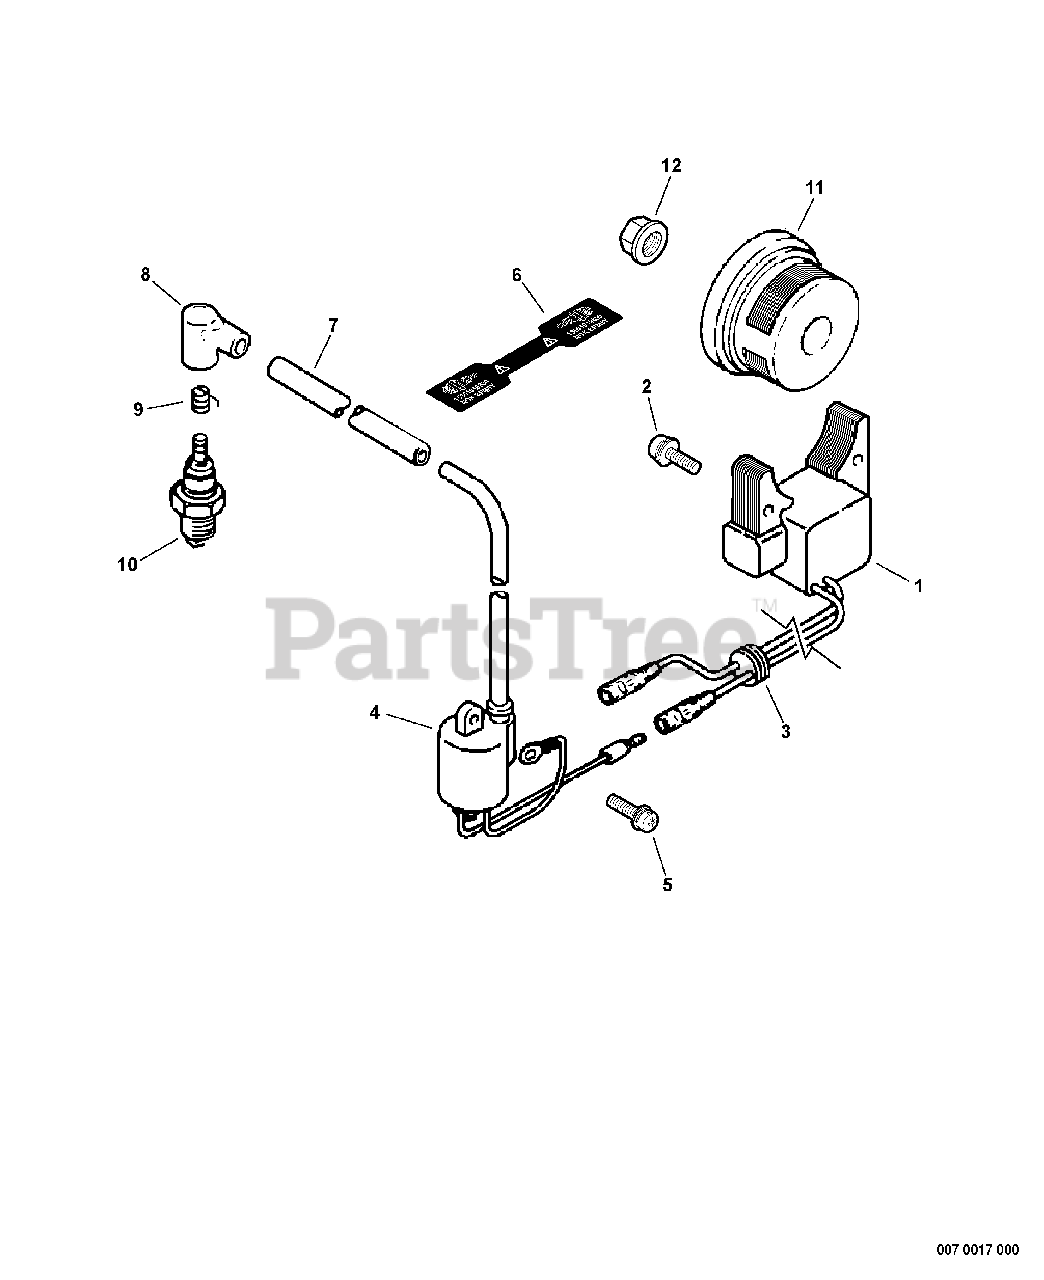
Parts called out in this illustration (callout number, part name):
1	COIL, IGNITION
2	SCREW 5×25
4	COIL, IGNITION
5	SCREW 4×16
6	LABEL - SPARK PLUG
7	TUBE, INSULATOR
8	CAP, SPARK PLUG
9	TERMINAL, SPARK PLUG
10	SPARK PLUG - BPM8Y
11	FLYWHEEL
12	NUT, FLANGE 10×1.25
